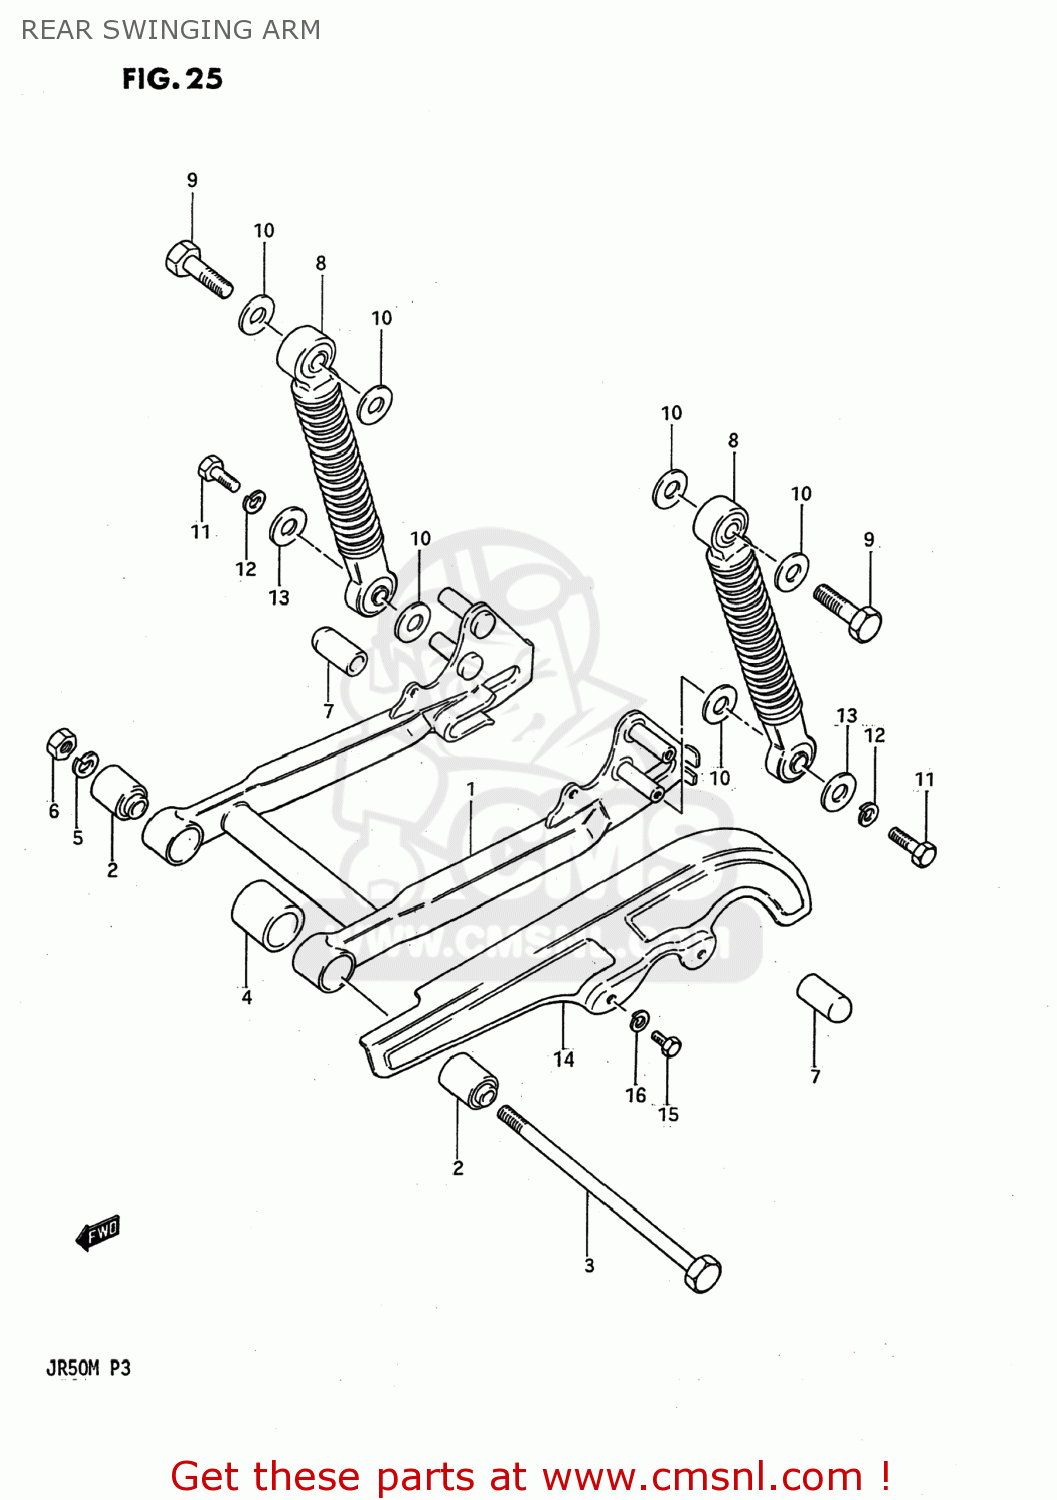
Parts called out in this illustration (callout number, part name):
1	ARM,REAR SWING
2	BUSH
3	SHAFT,RR SWINGINGARM PIVOT
4	CUSHION
5	WASHER,LOCK,10
6	NUT
7	CAP,RR SHOCK ABSORBER BOSS
8	ABSORBER ASSY,RR SHOCK
9	BOLT,M10X1.25X
10	WASHER
11	BOLT
12	WASHER,LOCK
13	WASHER (6.5X24X1.6)
14	CASE,CHAIN
15	BOLT
16	WASHER,LOCK
